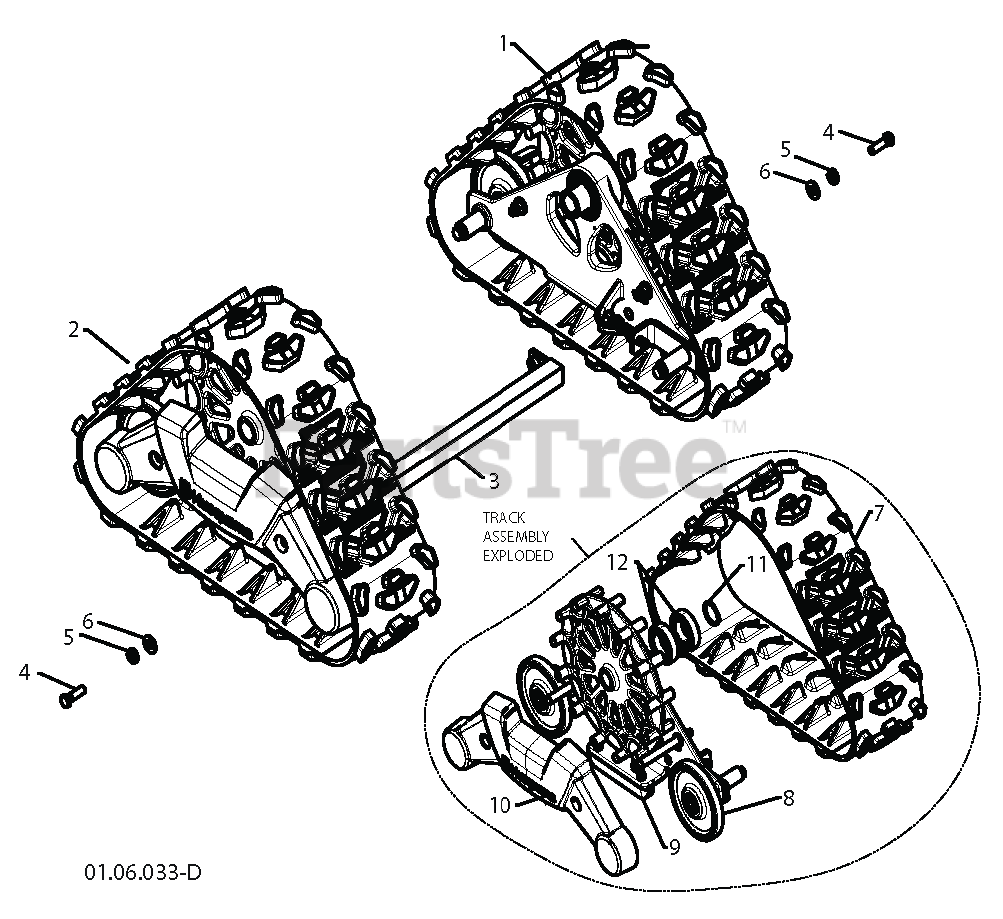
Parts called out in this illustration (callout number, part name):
1	WHEEL.ASM.TRACK.LH.12.SNOW
2	WHEEL.ASM.TRACK.RH.12.SNOW
3	SUPPORT.BRACE.ASM.TRACK.12
4	CAPSCREW.HEXHD.5/16X1.25.
5	LOCKWASHER
6	WASHER
7	BELT.TRACK.RUBBER.SNOW
8	WHEEL.IDLER.TRACK.SNOW
9	GUIDE.TRACK.SNOW
10	COVER.SIDE.TRACK
11	SNAP RING
12	BEARING.BALL.SHIELD.TRACK.SNOW
